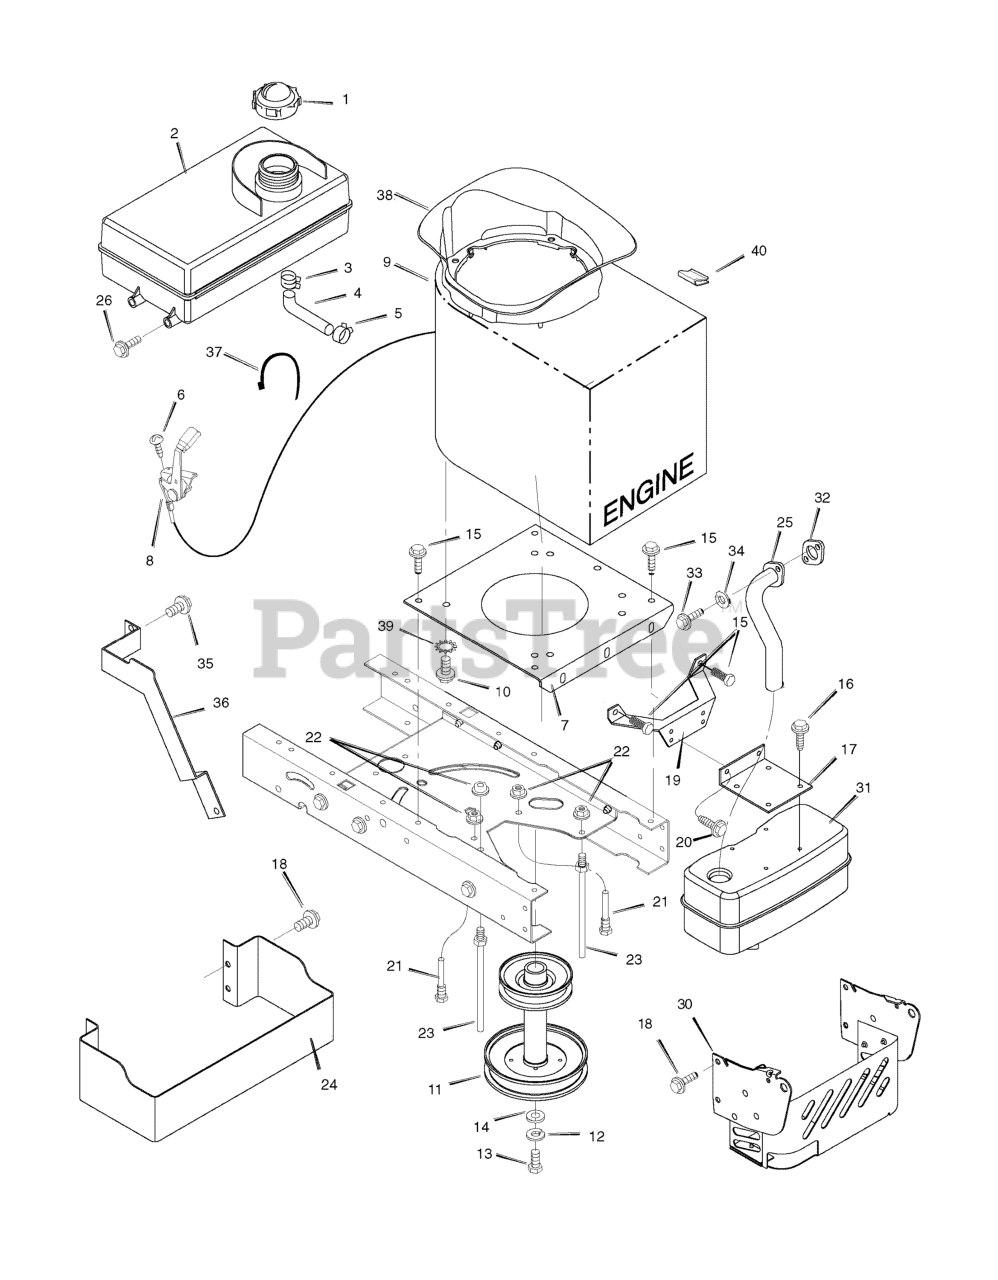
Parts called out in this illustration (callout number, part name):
1	Fuel Cap **
2	TANK, Fuel 1.4 Gal.
3	Hose Clamp
4	Fuel Line (Must cut to length)
5	Hose Clamp
7	Plate, Engine
8	Throttle Control
9	Engine, Briggs & Stratton *
10	Bolt, Engine Mount
11	STACK PULLEY ASSEMBLY
12	Lockwasher
13	Bolt, Hex
17	Bracket, Muffler
19	Bracket, Muffler Mount
21	Guide, Belt
22	Nut, Flange
23	Guide, Belt
24	Guard, Heat Shield
25	Exhaust Tube, Single
30	Shield, Heat
31	Muffler
32	GASKET, Exhaust
34	Washer
35	Bolt, Washer Hex Head
36	Guard, Exhaust Pipe
37	Tie, Strap Black
38	Plenum, X1 - M28/31
39	Washer, Star
40	Clip, Wire Adhesive
